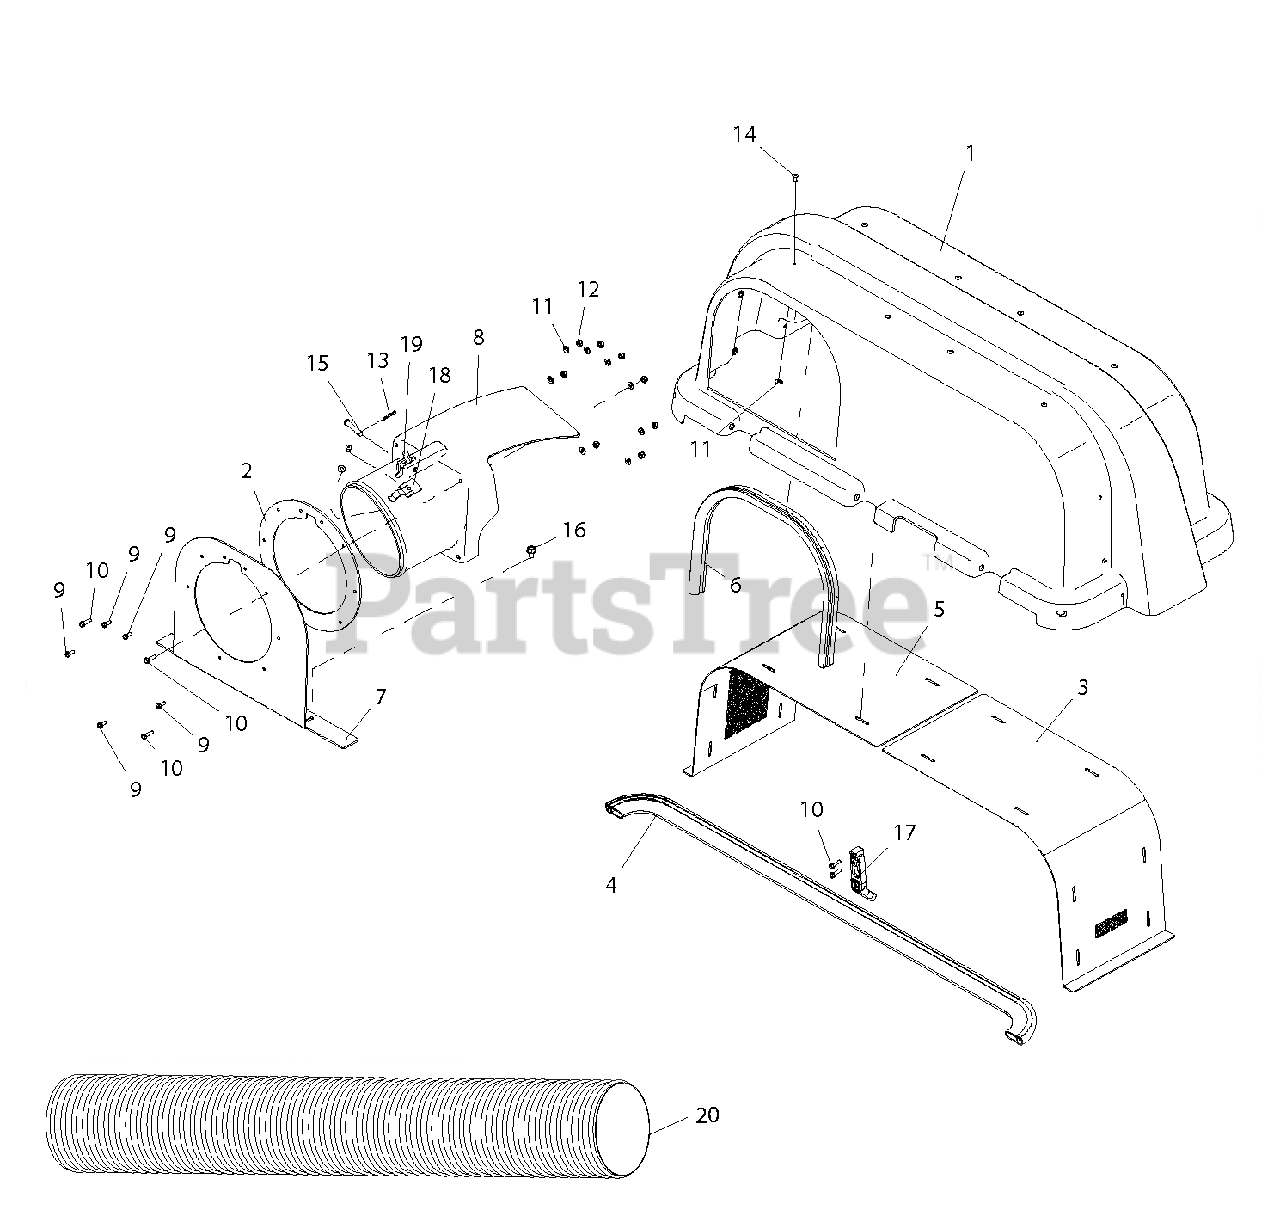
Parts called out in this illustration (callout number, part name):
1	COVER, 2-BUCKET BAGGER
2	SEAL, UPPER BOOT
3	WMT-BAGGER HOOD VENT, LH
4	SEAL, BULB - BAGGER HOOD
5	WMT-BAGGER HOOD VENT, RH
6	SEAL, BULK
7	WLDMT, TUBE SUPPORT
8	BOOT, UPPER
9	@SCR-MCH 10-24X.50 HWH YWZC
10	@SCR-MCH 10-24X.75 HWH YWZC
11	@WSHR-FL-STL.219X.50X.049 YWZC
12	@NUT-LK-NYL 10-24 W/INSRT YWZC
13	PIN-HAIR, ENDRIES #25 YWZC
14	.187X.6835 DOME ST
15	PIN-CLEV .309 X 1.625 YWZC
16	@SCR-TAP .31-18X.50 HWH TR YWZ
17	LATCH, RUBBER
18	THUMB LATCH
19	INDICATOR, FLOW
20	BAGGER, HOSE 51"
20	HOSE, FLEXIBLE-47"
